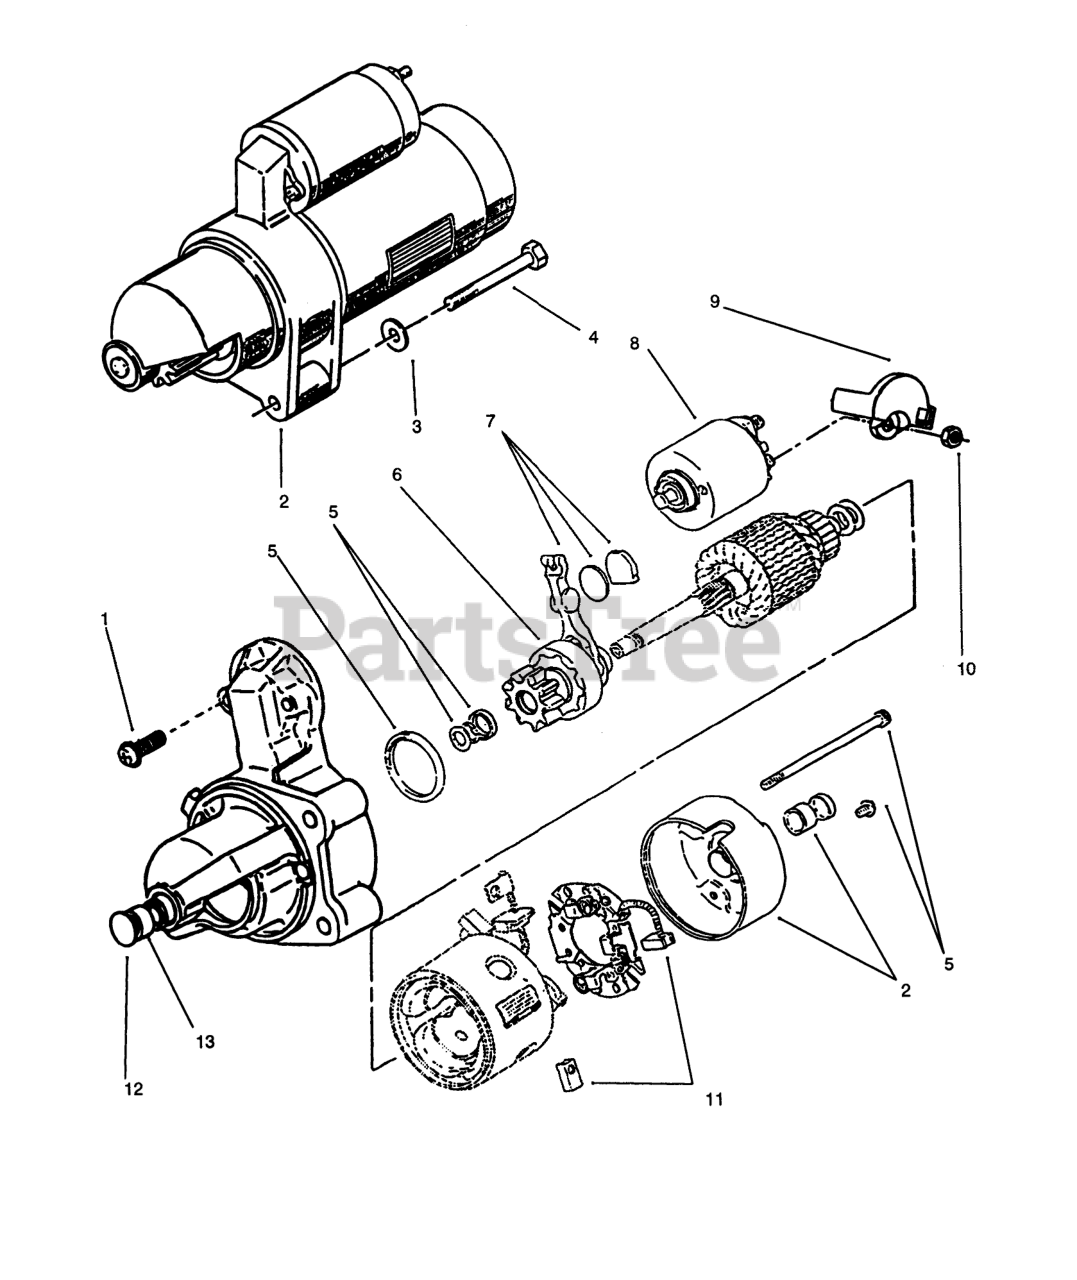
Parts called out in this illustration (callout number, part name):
1	Starter Hdwr Kit (Includes Solenoid Screws 2], Brush Holder Screws 2], Thru Bolts 2], Armature Shims 2], Pinion Stop Collar, & Pinion Retaining Ring)
2	STARTER
3	WASHER
4	SCREW
5	DUST-SEAL KIT
6	Clutch-Starter (Includes Pinion Gear w/Clutch)
7	Kit-Starter Shift Lever (Includes Shift Lever, Wear Plate & Rubber Plug)
8	Kit-Starter Solenoid (Includes Solenoid, Spring, & Plunger)
9	Cap-Starter Solenoid
10	Nut
11	Kit-Starter Brush (Includes Positive Brush 2] & Negative Brush w/Pigtail)
12	Kit-Bushing (Includes Front Bushing & Rear Cap w/Bushing)
13	Holder-Starter Brush (Includes Brush Holder w/Negative Brush)
